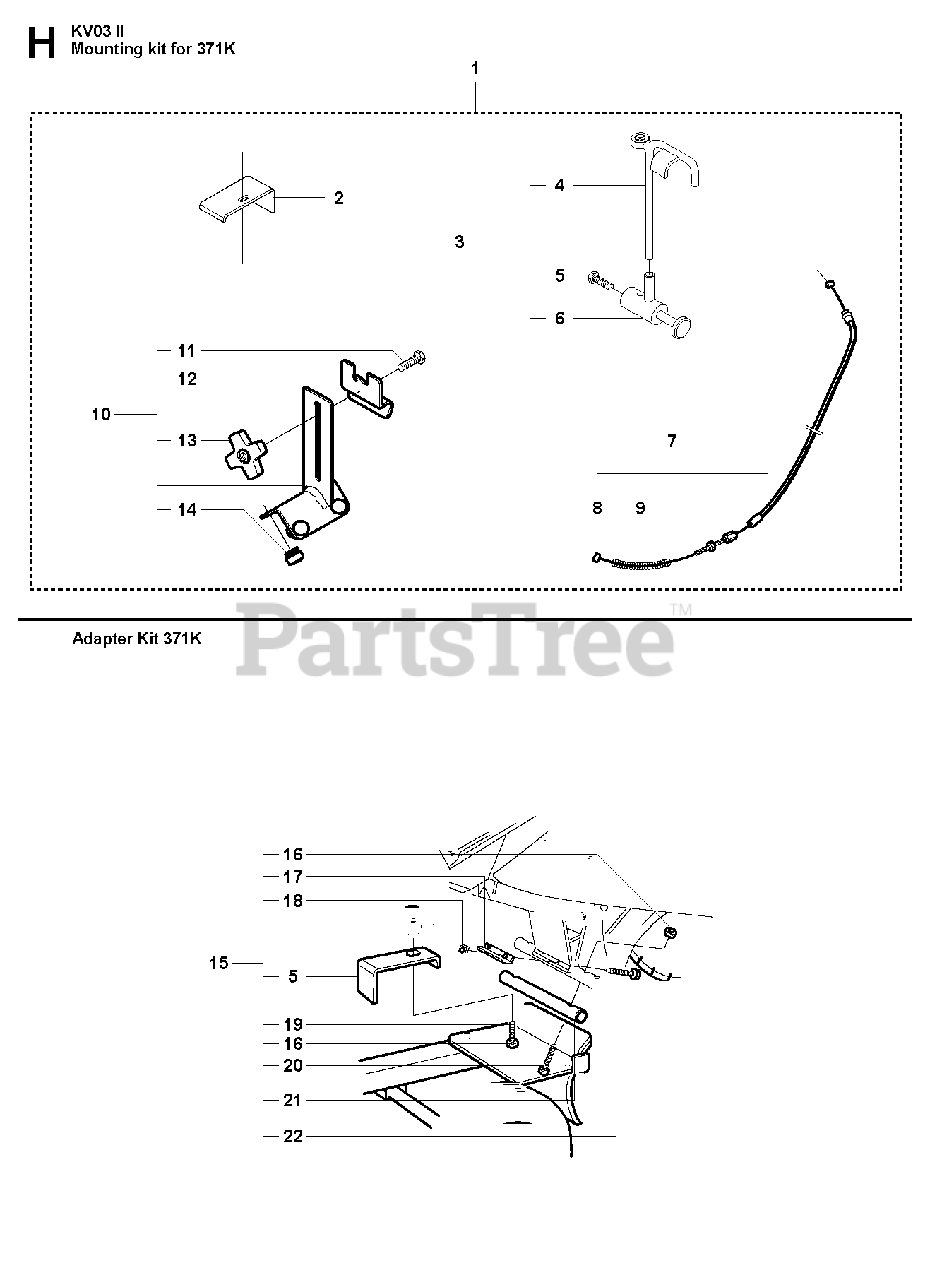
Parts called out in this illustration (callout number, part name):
1	ASSEMBLY KITIncl. 2, 3, 7, 10
3	THROTTLEIncl. 4, 5, 6
7	THROTTLE WIREIncl. 8, 9
10	RETAINERIncl. 11, 12, 13, 14
13	STEERING WHEEL
15	BRACKETIncl. 5, 16 - 22
16	HEXAGON NUT
21	SPACING TUBE
